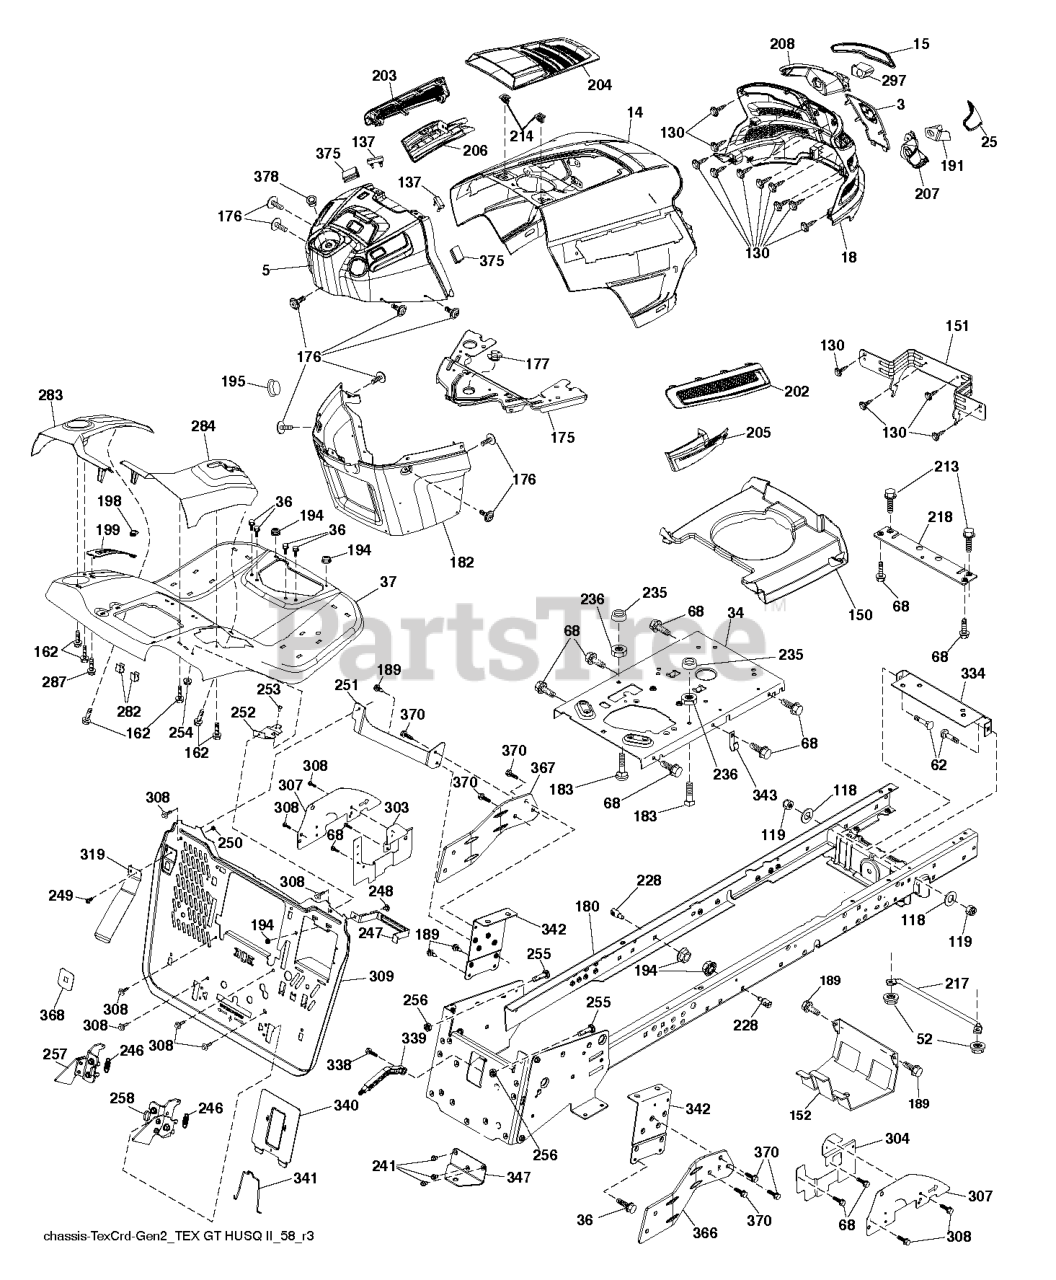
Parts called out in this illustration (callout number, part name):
3	APPLIQUE.SUBASM.GT.HUSQ.II
5	DASH.ASM.W/BUMPERS.READYSTART
14	HOOD.ASM.HUSQVARNA.GT.TEX.ORAN
15	LENS.HEADLIGHT.LH.GTII.2011
18	GRILLE SUBASM.GT.II.LOW.HDLGHT
25	LENS.HEADLIGHT.RH.GTII.2011
36	SCREW 5/16"
37	FENDER.TEX.SRD.CRD.BASE
118	WASHER PLAIN WASHER 3/8 X 0.08
137	BUMPER DASH
150	AIR.DUCT.GTV.BLACK
151	BRACKET.PIVOT.HOOD.GT.HUSQ.II
152	SHIELD.BROWNING.W/TEX
175	PLATE.PNT.CROSSMEMBER.HUSQ/PRE
176	SCREW.#10-24X5/8.RN.QU
177	BUSHING STEERING
180	CHASSIS WELDMENT.CRD2.BKP_BLTS
182	DASH LOWER.HUSQ.PRED NO CRUISE
189	SCREW
191	INSERT.REFLECTIVE.RH.HUSQ.GTII
195	PLUG.HOLE.DASH.LOWER.12V.BLK
198	INDICATOR.DECK.LIFT.RED
199	PLATE DECK LIFT
202	VENT.SIDE.RH.GT.HUSQ.II.
203	VENT.SIDE.LH.GT.HUSQ.II.498
204	VENT.TOP.ASM.HUSQ.GT2
205	SIDE.TRIM.RH.GT.HUSQ.II
206	SIDE.TRIM.LH.GT.HUSQ.II.GRAY
207	HEADLIGHT.CUP.BEZEL.HUS.GT2.RH
208	HEADLIGHT.CUP.BEZEL.HUS.GT2.LH
213	SCREW HEXAGON HEAD SCREW 5/16-
214	CLIP.RETAINER.TINNER.
217	ROD.PIVOT.HOOD
218	X-PIECE.HOOD.STOP.NON/
228	STUD.W/"D"ANTI-ROTATION
236	NUT.CENTERLOCK.5/16-
246	SPRING.LTCH.BGR.GEN2.5.CRD.TEX
247	STRAP.BATTERY.TCRD.GEN2.5X431
248	BOLT.CARR.5/16-18X1/2
249	SCREW.BUTTONHD.10-24X1/2.(2 2)
251	BRACKET.PNT.LH.SUPP.BKPLT.EDIP
252	BRACKET.PNT.RH.SUPP.BKPLT.EDIP
253	BOLT CUP HEAD SQUARE NECK BOLT
254	NUT T
257	LATCH.ASM.BGR.LH.GEN2.5.STMPD
258	LATCH.ASM.BGR.RH.GEN2.5.STMPD
282	CLIP.RETAINER.CONSOLE.LT.HUSQ
283	CONSOLE.DECKLIFT.CRDII.498
284	CONSOLE.PEDAL.HYDRO
287	SCREW 1/4X20
297	INSERT.REFLECTIVE.LH.HUSQ.GTII
303	SHIELD.LWR.LH.30DECK/CRD1&2
304	SHIELD.LWR.RH.30DECK/CRD2PEDAL
307	SHIELD.UPPER.CRD.SRD.ISO
308	BOLT.5/16-18UNCX3/4 W/SEMS.BLK
309	BACKPLATE.TEXCRD2.5.BAGGER.479
319	LEVER.PRSNC.BGR.TEX.CRD.GEN2.1
334	BRACKET.ENGINE
339	LEVER LEVER BAGGER
340	BATTERY.DOOR.TCRD.GEN2.5.MS479
341	LATCH.BATTERY.DOOR.TCRD
342	SUPPORT SUPPORT FENDER
343	CLIP CLIP
347	HITCH HITCH TOW TEX CRD GEN 2
366	BRACKET.RH.FRONT.BAGGER.BLACK
367	BRACKET.LH.FRONT.BAGGER.BLACK
368	FULL.LEVER.BAGGER.TEX.CRD
370	SCREW 3/8-16X1
375	BUMPER CLIP-ON. DASH 1"
378	BUSHING FLANGE; PLASTIC
